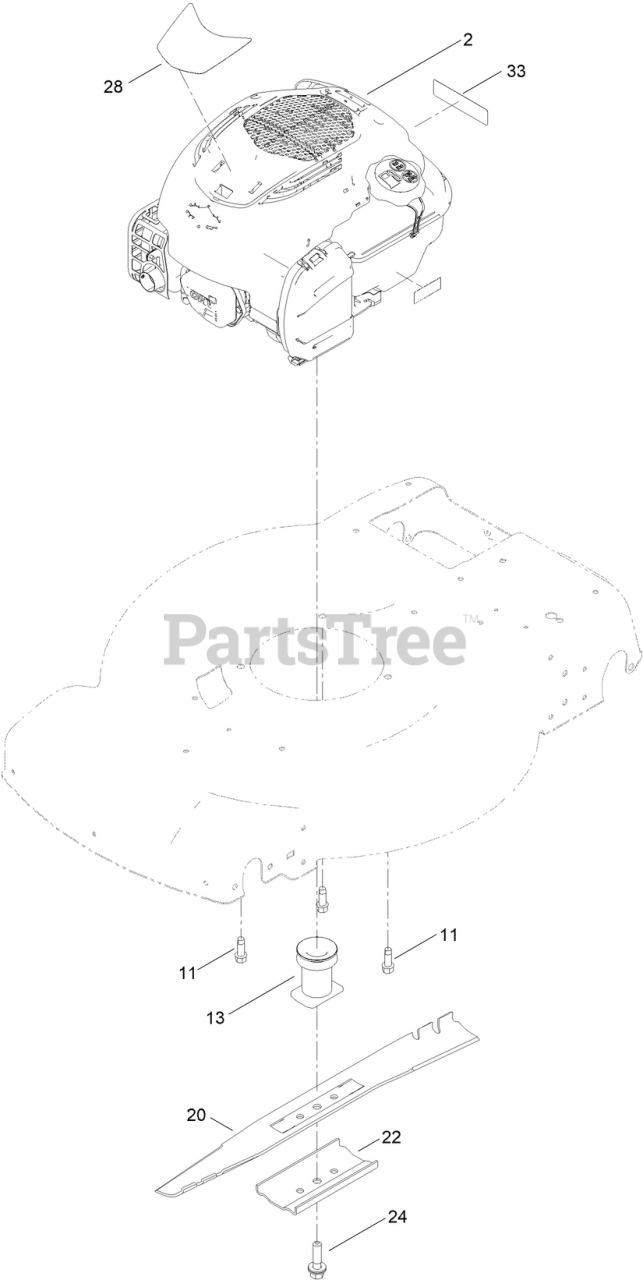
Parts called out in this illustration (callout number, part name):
11	SCREW-THD FORM, HWH
13	DRIVER-BLADE
20	BLADE-22 INCH
22	SUPPORT-BLADE
24	BOLT-BLADE
28	DECAL - BRIGGS 725 EX
33	DECAL-ARRESTOR, SPARK
